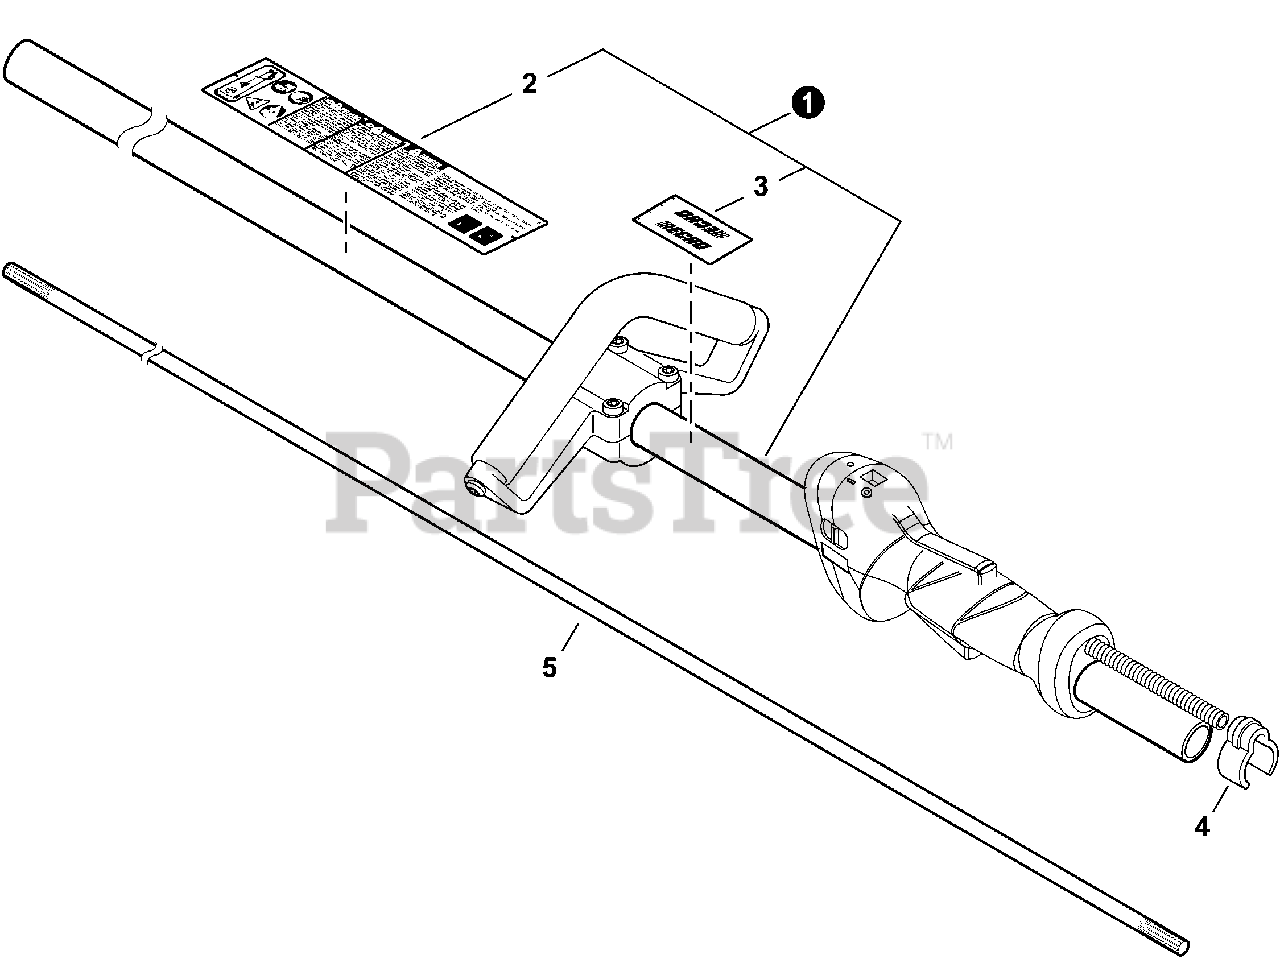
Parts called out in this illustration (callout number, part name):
1	MAIN PIPE ASSY
2	LABEL, CAUTION
3	LABEL, HANDLE LOCATION
4	CLIP, CABLE 25 MM
5	SHAFT, DRIVE
